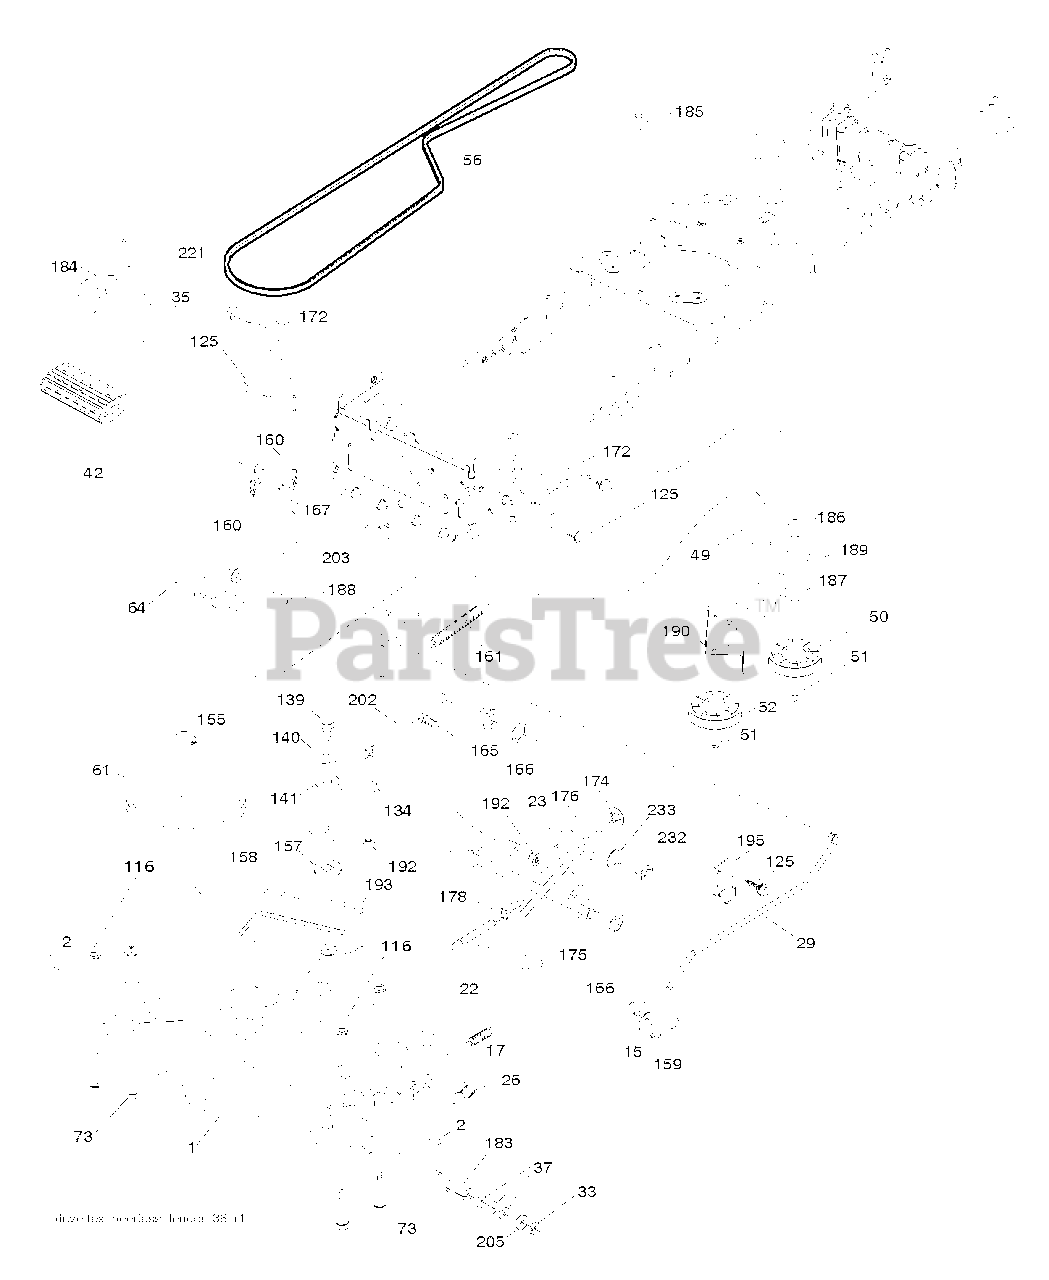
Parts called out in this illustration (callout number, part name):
2	SQUARE KEY
15	WASHER
17	SPRING.BRAKE.PEERLESS.TEX
23	KNOB.DUCKHEAD.1/2
26	SPRING.BRAKE.RTN.GR.DR
29	ROD.BRAKE.PEERLESS
35	ROD.CNTRL.PARK.PREDATOR.LT.TEX
42	PEDAL COVER T
50	IDLER.FLAT.910.OFFSET
51	NUT LOCK FLG 3/8-16 UNC
52	IDLER.V-GROOVE.910.OFFSET
56	V-BELT.TRACTOR.DRIVE.P
61	PULLEY TRANS
64	SHAFT.ASM.PEDAL.BRAKE.
116	NUT LOCK HEX FLANGE 5/16-18
125	SCREW
139	BOLT 1/4-28X3/4
140	LOCKWASHER
155	RETAINING RING LT
157	WASH-SHFT PLT LT
158	KEEPER.PMS.18/20.D4365
159	COTTER PIN
160	RETAINER CLIP
161	SPRING, RETURN LT
165	BUSHING.SHAFT.BRAKE.HAND
166	NUT.PUSH.625
167	LATCH.BRAKE.SPRING
172	STRAP.TRQ.LH.GEAR.DRIV
174	NUT.PUSH.500.2006
175	SHAFT ASM SHIFT
176	ARM.CLEVIS.ROD.SHIFT
178	SPRING.SHIFT.GT2006
183	SPACER AXLE
184	HANDLE.PARKING.BRK.PRED.LT.RED
186	SPACER.RETAINER
187	WASHER 12/32X2X10GA
188	RP LINK.CLUTCH.GROUND.DRIVE
189	BELLCRANK.GROUND.DRIVE.TEX.
190	KEEPER.BELLCRANK.DRIVE
192	NUT LOCK CENTER 1/4 -28 FNTHD
193	SCREW 5/16"
195	BRKT.ROD.BRAKE.PEERLES
202	LINK.SHIFT.PMST.18" (SPG1286)
203	WASHER
221	RETAINER.SPRING.CLIP.H
232	BOLT FIN HEX 7/16-14 X 1
233	WASHER SERRATED
